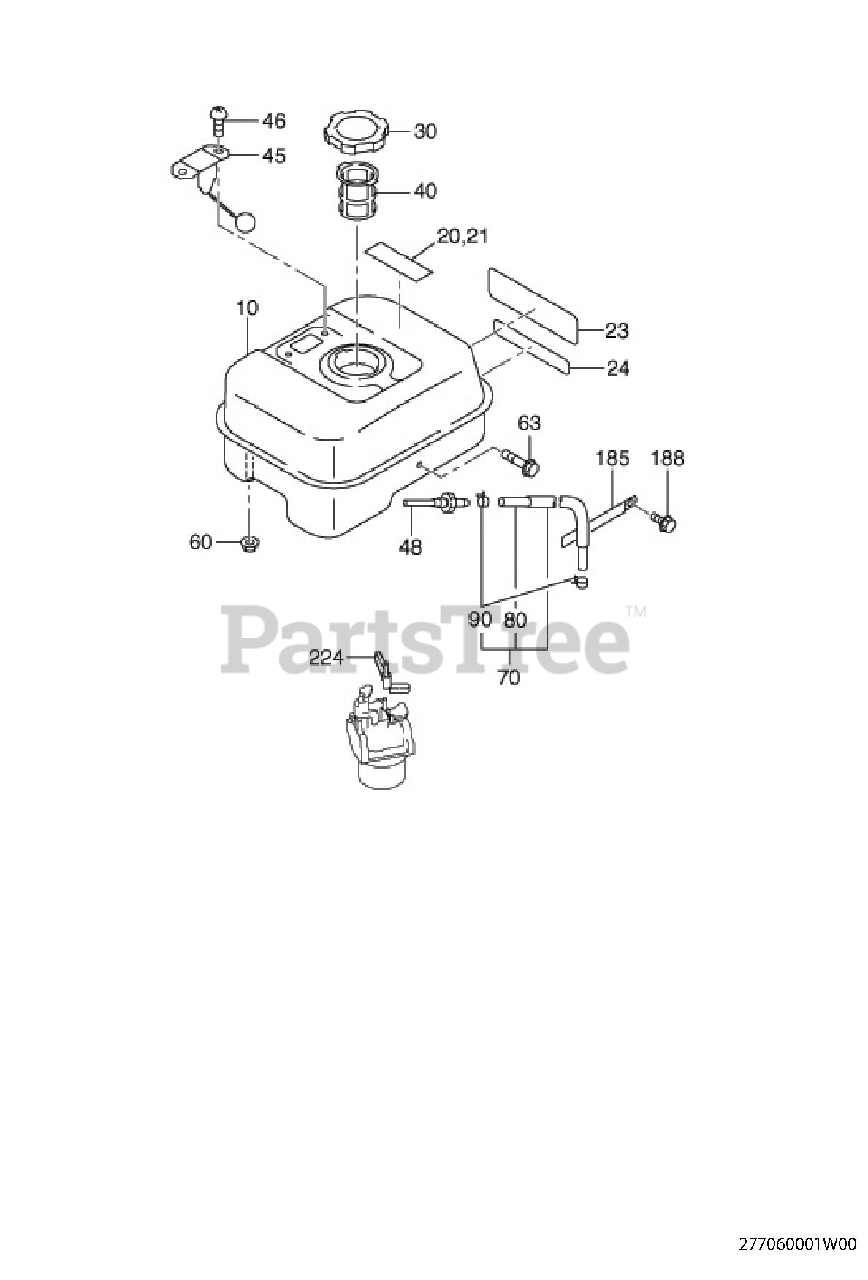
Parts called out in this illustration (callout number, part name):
10	FUEL TANK CP
20	LABEL, WARNING
30	FUEL TANK CAP CP
224	CHOKE LEVER CP
